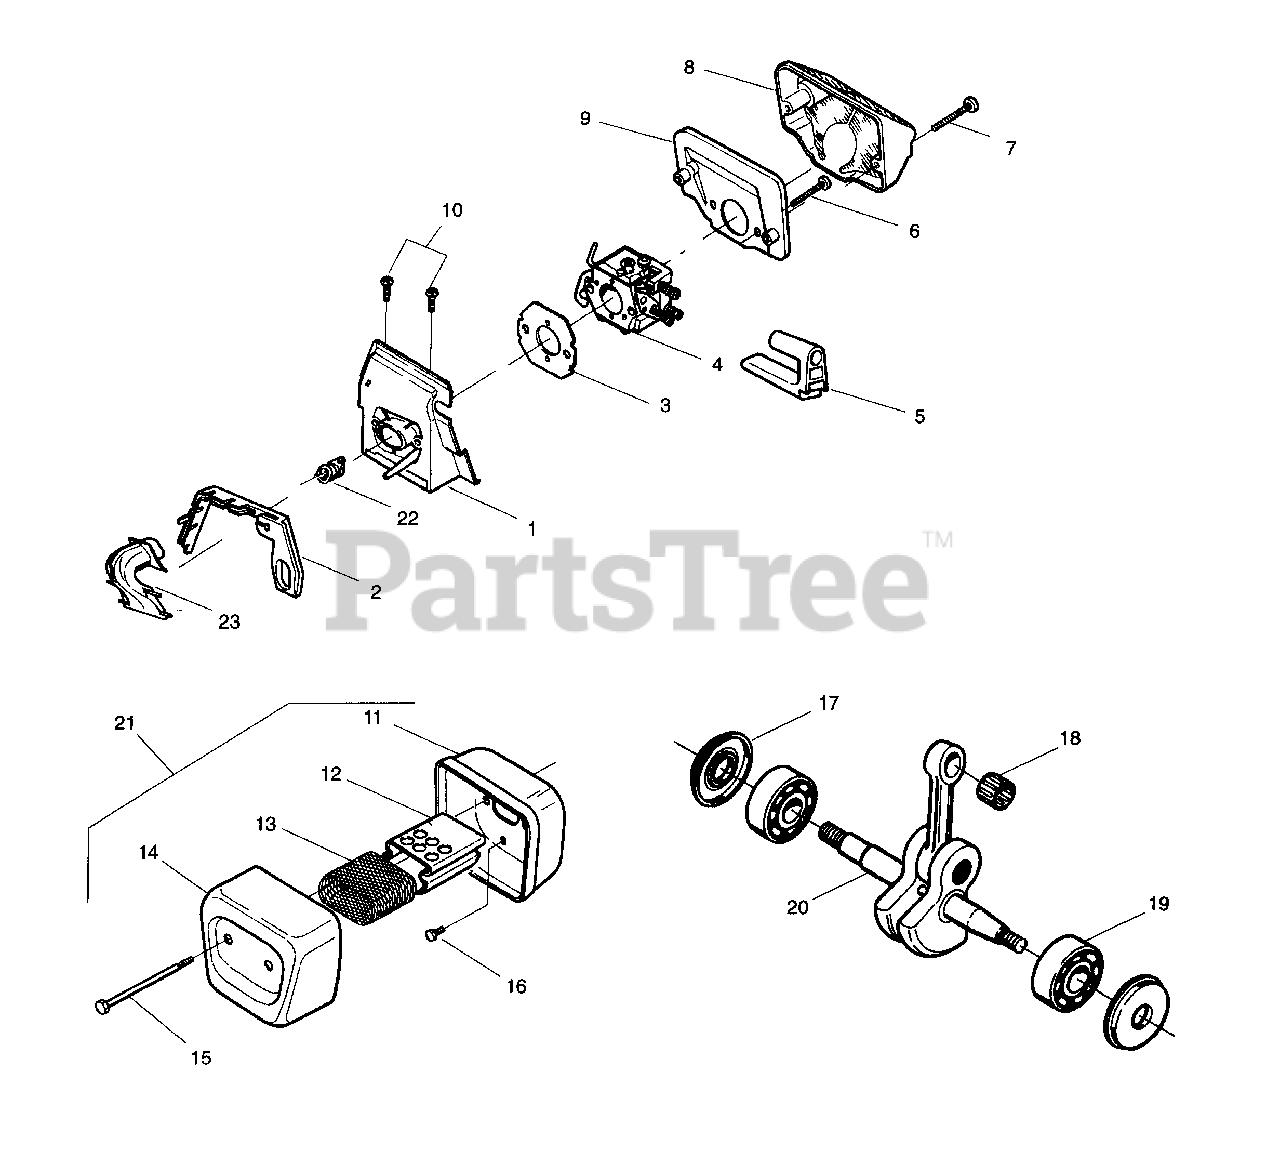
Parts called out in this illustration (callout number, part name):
1	Cam-Adaptor
2	Turbo Clean Seal
3	Carburetor Gasket
4	Carburetor
5	Grommet-Final
8	Air-Filter - Top
10	Screw
11	Muffler Body
12	Muffler Diffuser
13	Spark Arrestor Screen
14	Muffler Cover
16	Muffler Bolt
17	Crankshaft Seat
18	Piston Pin Bearing
19	Crankshaft Bearing
20	Crankshaft & Rod Assembly
21	Muffler Kit
22	Intake Sleeve
23	Turbo Air Cleaner Assembly
